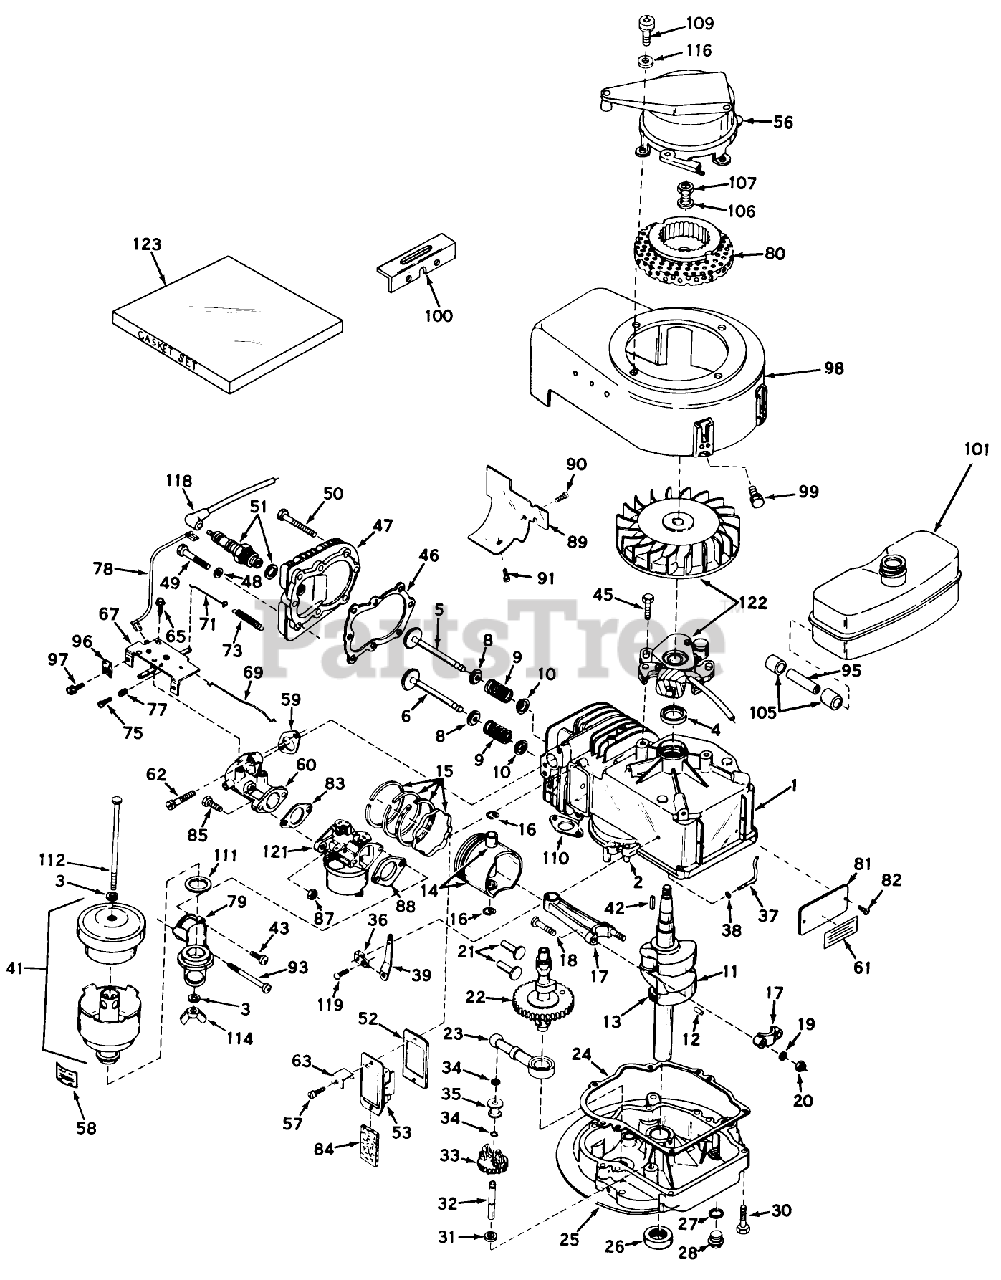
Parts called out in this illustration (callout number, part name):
1	Cylinder Assy. (Incl. Ref. 2 4)
1	Cylinder Assy. (Incl. Nos. 2 4)(Use with Model LAV35-40152G only)
2	Pin-Dowel
3	Washer Fibre
5	Valve, Intake (Incl. Ref. #38, 39 40) (Std.)
5	Valve, Intake(1/32"overs.)(Incl. Ref. 8, 9 10)
6	Valve, Exhaust (Standard)(Incl. Ref. 8, 9 10)
6	Valve, Exhaust (1/32" Overs.(Incl. Ref. 8, 9 10)
8	Cap-Upper Valve Spring
9	Spring-Valve
10	Cap-Valve, Spring
11	Crankshaft Assy. (Incl. Ref. 12 13)
11	Crankshaft Assy. (Incl. Ref. 12 13)(Model LAV35-40455H)
12	Pin, Groove
13	Gear, Crankshaft
14	Piston Pin Assy. (Standard)(Incl. 2 of No. 16)
14	Piston Pin Assy. (.010 overs.)(Incl. 2 of Ref. 16)
14	Piston Pin Assy. (.020 overs.)(Incl. 2 of Ref. 16)
14	Piston Pin Assy. (Incl. 2 of No. 16)(Standard)
14	Piston Pin Assy. (Incl. 2 of No. 16)(.010 oversize)
14	53020 ADN. TO 28594
15	Ring Set, Piston (Std.)
15	Ring Set, Piston (.010 o.s.)
15	Ring Set, Piston (.020 o.s.)
15	Piston Ring Set Std.
15	Piston Ring Set .010 O.S.
15	Piston Ring Set .020 O.S.
16	Ring-Retaining, Piston Pin
17	Rod Assy., Connecting (Incl. Nos. 18, 19 20)
18	Bolt, Connecting
19	Washer
20	LOCKNUT
21	Lifter-Valve
22	Camshaft
23	Oil Pump ASM
25	Flange Assy., Mounting (Incl. Ref. 26, 27, 28 32)
25	Flange Assy., Mounting (Incl. Nos. 26, 27, 28 32)(LAV30-30265G only)
28	Plug Oil Drain
30	Screw (1/4-20 x 1-1/4)
31	Washer-Flat
32	Shaft-Governor
33	Governor Gear ASM
34	Ring-Retaining
35	Spool-Governor
36	Clamp-Lever, Governor
37	Rod, Governor (Incl. No. 36)
38	Washer-Flat
39	Lever, Governor
41	Cleaner Assy., Air
42	Key Flywheel
43	KIT - SEAL WIPER
45	Screw
47	CYLINDER HEAD
48	Washer
49	Screw
50	Screw
51	SPARK PLUG
53	Breather Assembly (Incl. Nos. 52 84)
56	Starter, Impulse
57	Screw
58	Decal, Air Cleaner
60	Pipe, Intake
61	480B GIL SNWTHWR O/
62	Screw, Fil. Hd. Sems
63	Retainer Clip
65	Screw (10-24 x 9/16)
67	Control Assy., Speed
69	Link, Throttle to Governor
71	Link, Governor Spring
73	Spring, Governor
75	Screw
77	Spring-Compression
78	Wire, Ground
79	Elbow, Air cleaner
80	Hub Screen
81	IDENTIFICATION PLATE
82	Stud
84	Element-Breather
87	Nut and Lock Washer (1/4-28)
89	Extension, Housing (Use with Model LAV35-40152G only)
90	Screw
91	Screw
93	Screw
95	Line, Fuel
96	Conduit
97	Screw (10-32 x 3/8)
98	Housing, Blower
99	Screw (1/4-20x19/32)
100	Bracket, Shroud
101	Tank, Fuel
102	Cap, Fuel Filler
105	Line-Fuel (8.62)
106	Washer
107	Nut, Flywheel
109	Screw
112	Bolt, Air Cleaner
114	Nut, Wing
116	Washer
118	Cover-Spark Plug
119	Screw
121	Carburetor
122	Magneto, Tecumseh
123	Gasket Set
